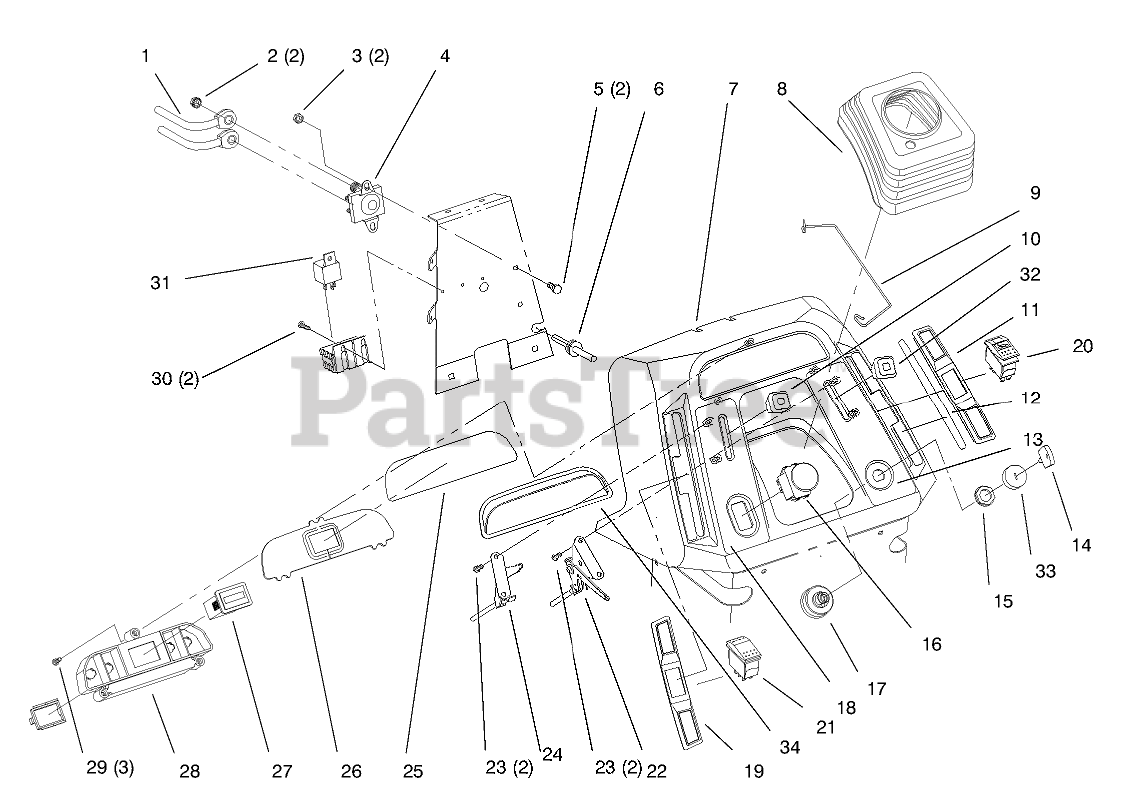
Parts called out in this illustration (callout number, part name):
1	WIRE-21 INCH
2	NUT-KEPS
3	NUT-LOCK, NI
4	Solenoid
5	SCREW-HH
6	GROMMET-RUBBER
8	BOOT-STEERING
9	CLIP-BOOT
12	DECAL - SHIFT
13	DECAL-THROTTLE, IGNITION
14	KEY-IGNITION
16	SWITCH-PTO
17	SWITCH-IGNITION
18	DECAL-PTO / CHOKE
19	COVER-SLOT, LH
22	CONTROL - THROTTLE
24	CONTROL-CHOKE
25	DECAL - DASH, LENS
26	LENS-DASH
27	HOURMETER
28	HOUSING-LIGHT, INDICATOR
29	SCREW
30	SCREW-PPHTF
31	RELAY
